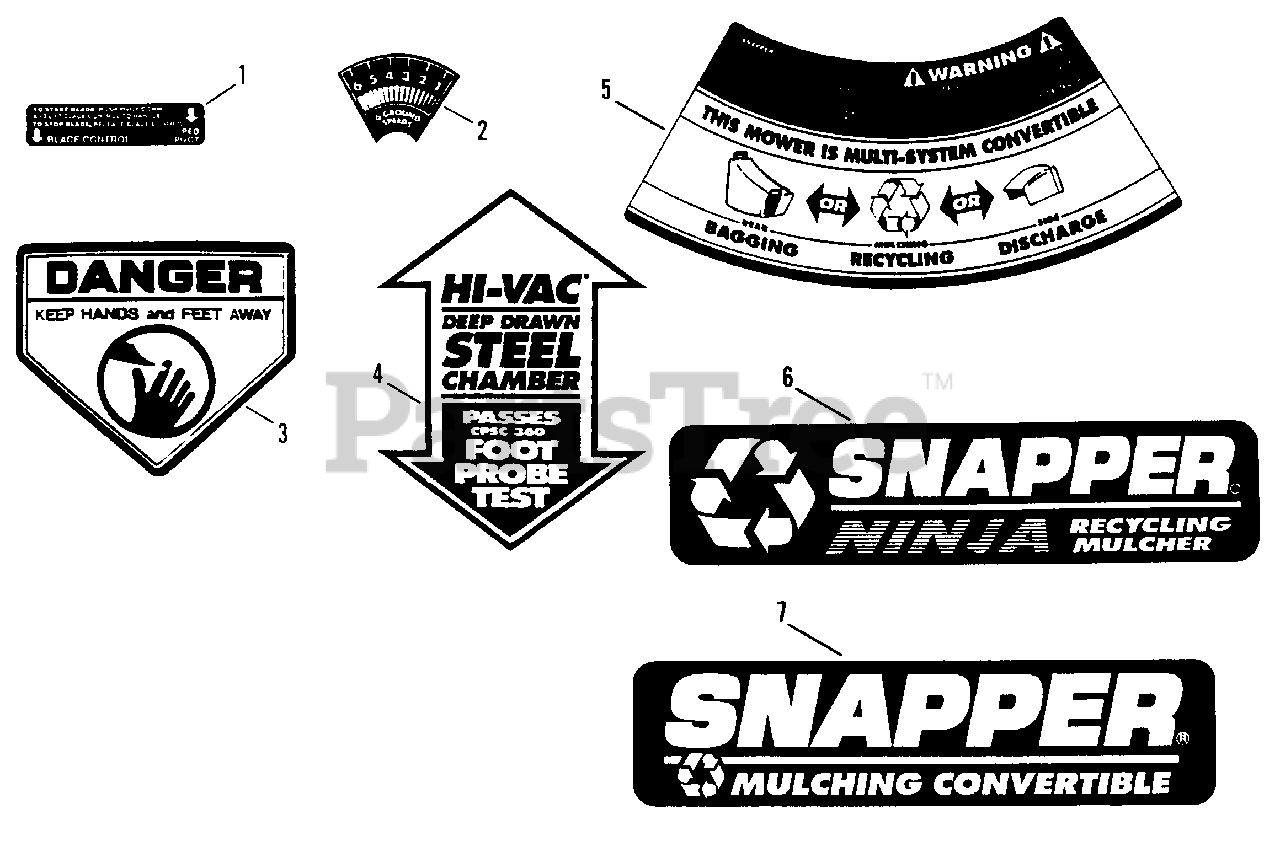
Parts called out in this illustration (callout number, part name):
1	DECAL, Blade Control
2	DECAL, Speed Sector
3	DECAL, DANGER (Keep Hands & Feet Away)
4	DECAL, Hi-Vac/Foot Probe (Red)
5	DECAL, Serial Blank (Large)
6	LOGO, Recycling Mulcher (Ninja)
7	LOGO, Mulching Convertible
